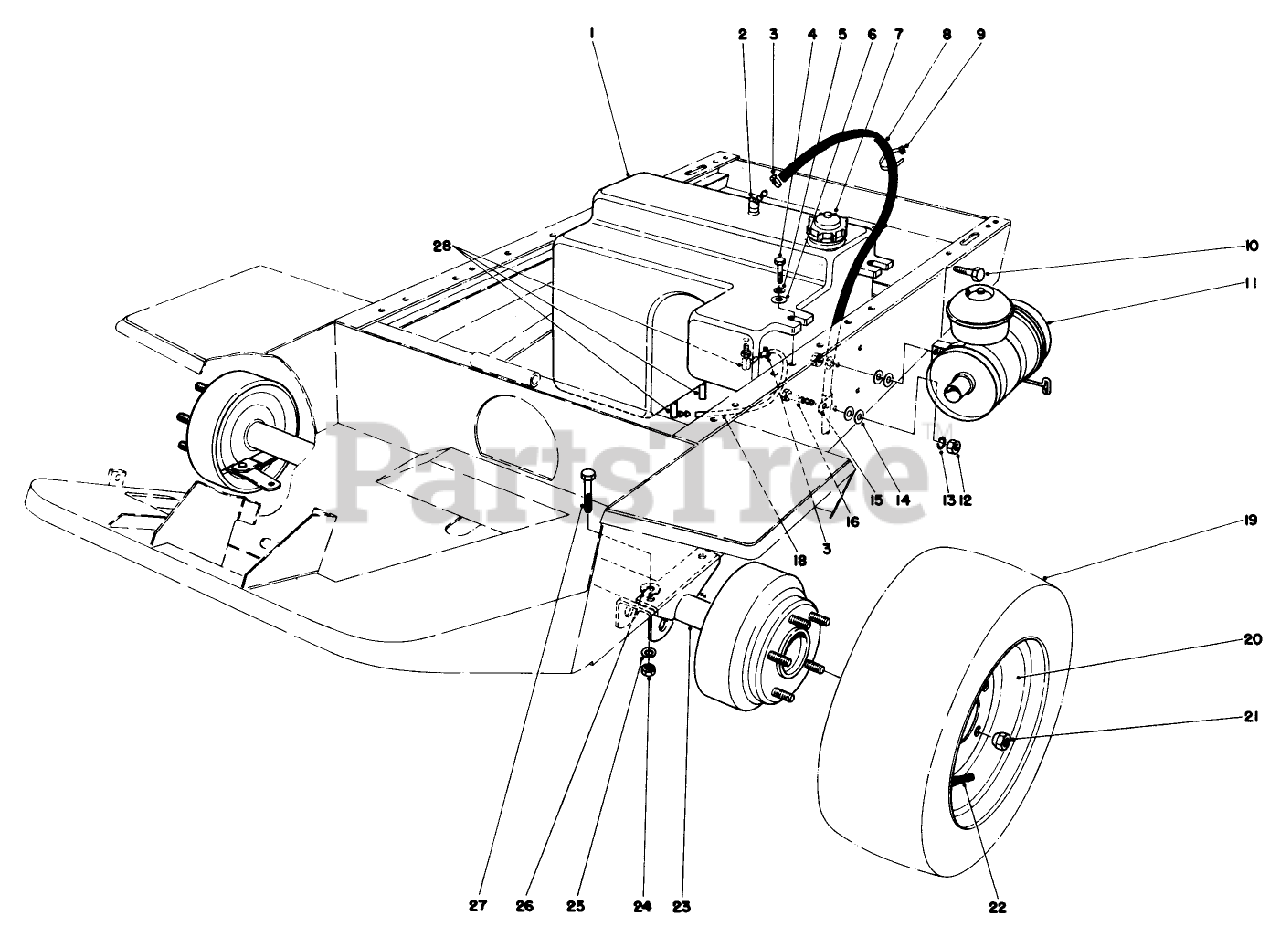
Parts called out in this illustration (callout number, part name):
1	GAS TANK
2	ELBOW
3	CLAMP-HOSE
4	SCREW-HH
5	WASHER-LOCK
6	WASHER
7	Gas Cap
8	GAS TANK VENT HOSE
9	Strap
10	SCREW-HH
11	AIR CLEANER ASM SERV
12	NUT-HEX
13	Lockwasher
14	WASHER-PLAIN
15	CLAMP-R
16	SCREW-HH
18	HOSE-FUEL
19	20 X 8.00 - 10 TIRE
20	WHEEL ASM
21	NUT-WHEEL
22	VALVE STEM AND CAP ASM
24	NUT-HEX
25	WASHER-LOCK
26	SPECIAL WASHER
27	SCREW-HH
28	FITTING-ELBOW, 90 DEG
